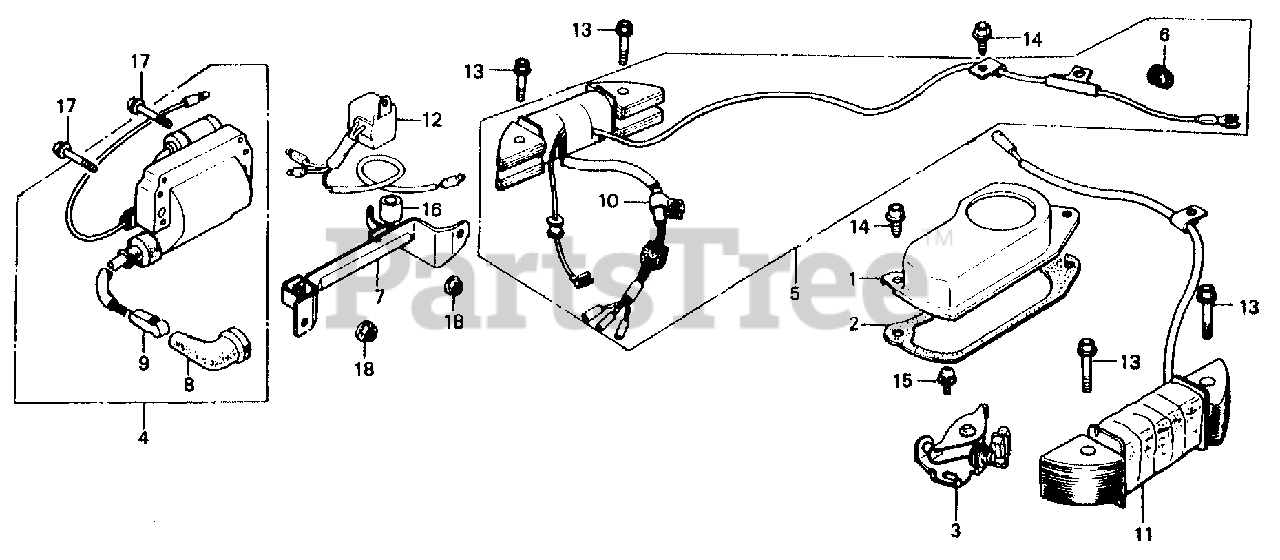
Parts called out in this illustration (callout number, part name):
1	COVER, BREATHER
2	GASKET, COVER
3	POINTS ASSY.
4	COIL ASSY., A.C. IGNITION
4	COIL ASSY., A.C. IGNITION (NOT AVAILABLE)
5	COIL ASSY., PRIMARY
6	GROMMET, PRIMARY WIRE
7	STAY, IGNITION COIL & CONTROL MODULE
8	CAP, IGNITION (SUMITOMO)
8	CAP, IGNITION (TOYO)
9	TERMINAL, PLUG
10	CLAMP, IGNITION WIRE
11	COIL ASSY., LAMP
12	RECTIFIER, SILICON
13	BOLT, FLANGE (6X40)
14	BOLT, FLANGE (5X14)
15	SCREW-WASHER (5X12)
16	TUBE, WIRE
17	SCREW-WASHER (6X25)
18	NUT, FLANGE (6MM)
